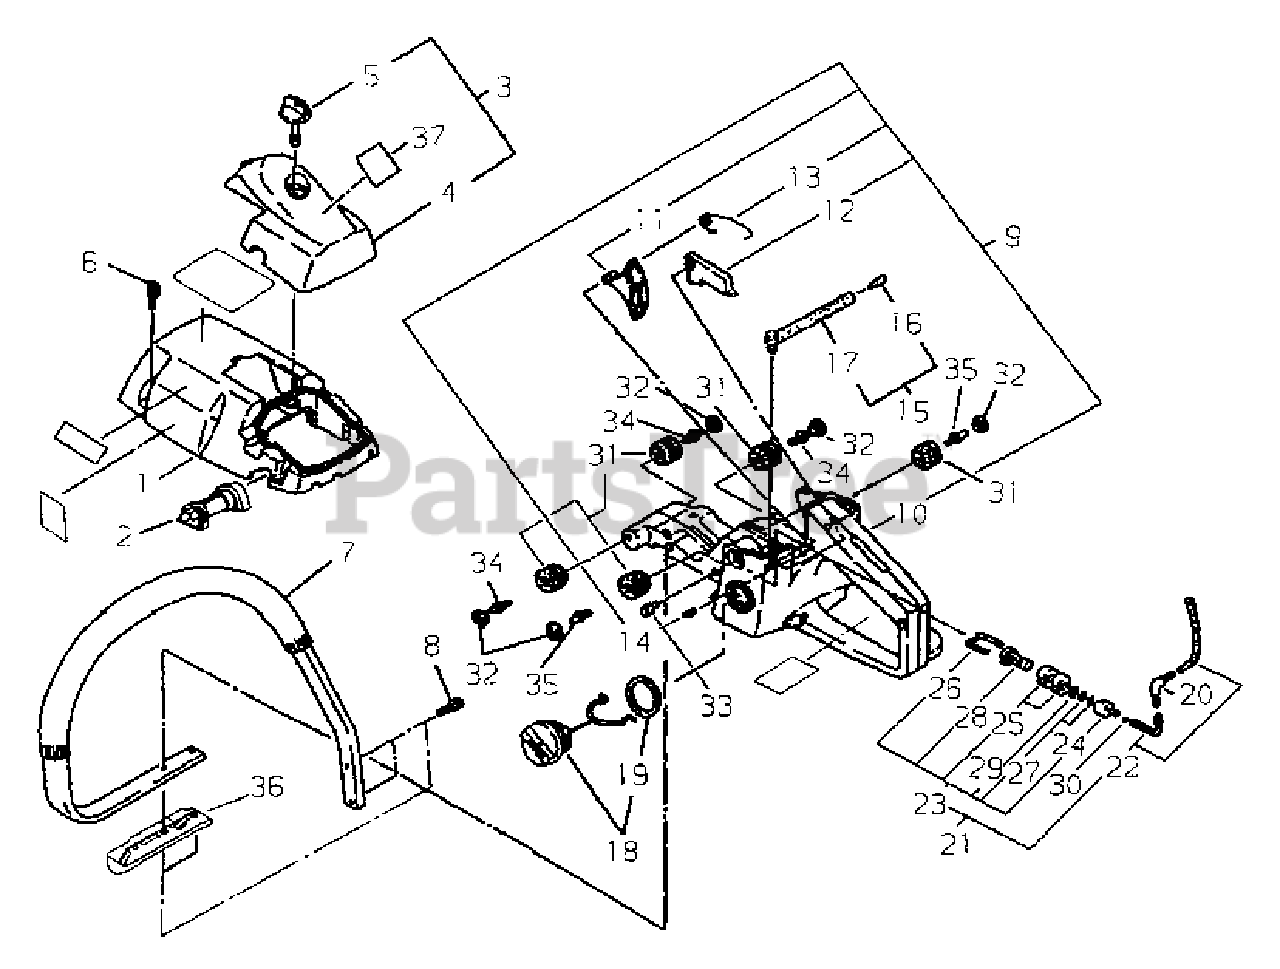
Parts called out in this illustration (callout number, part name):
1	COVER, ENGINE
3	AIR FILTER COVER ASSY
4	COVER, AIR FILTER
5	THUMBSCREW
6	SCREW - 4X16
7	HANDLE - FRONT
8	SCREW - 4X18
9	HANDLE ASSY - REAR
10	HANDLE - REAR
11	TRIGGER, THROTTLE
12	LEVER, LOCK
13	SPRING
14	PIN - 4X25
15	VENT, FUEL TANK
16	ELEMENT, BREATHER
17	PIPE - BREATHER
18	CAP ASSY
19	GASKET
20	JOINT
21	FUEL PIPE ASSY
22	PIPE - FUEL
23	FILTER, FUEL
24	WEIGHT, FUEL FILTER
25	FILTER, FUEL
26	CLIP, FILTER
27	SCREEN, FILTER
28	CASE, FILTER
29	RING, RETAINING
30	RING, RETAINING - 6
31	CUSHION - 22
32	PLUG - 22
33	CUSHION
34	BOLT
35	BOLT
37	LABEL - INSTRUCTION
